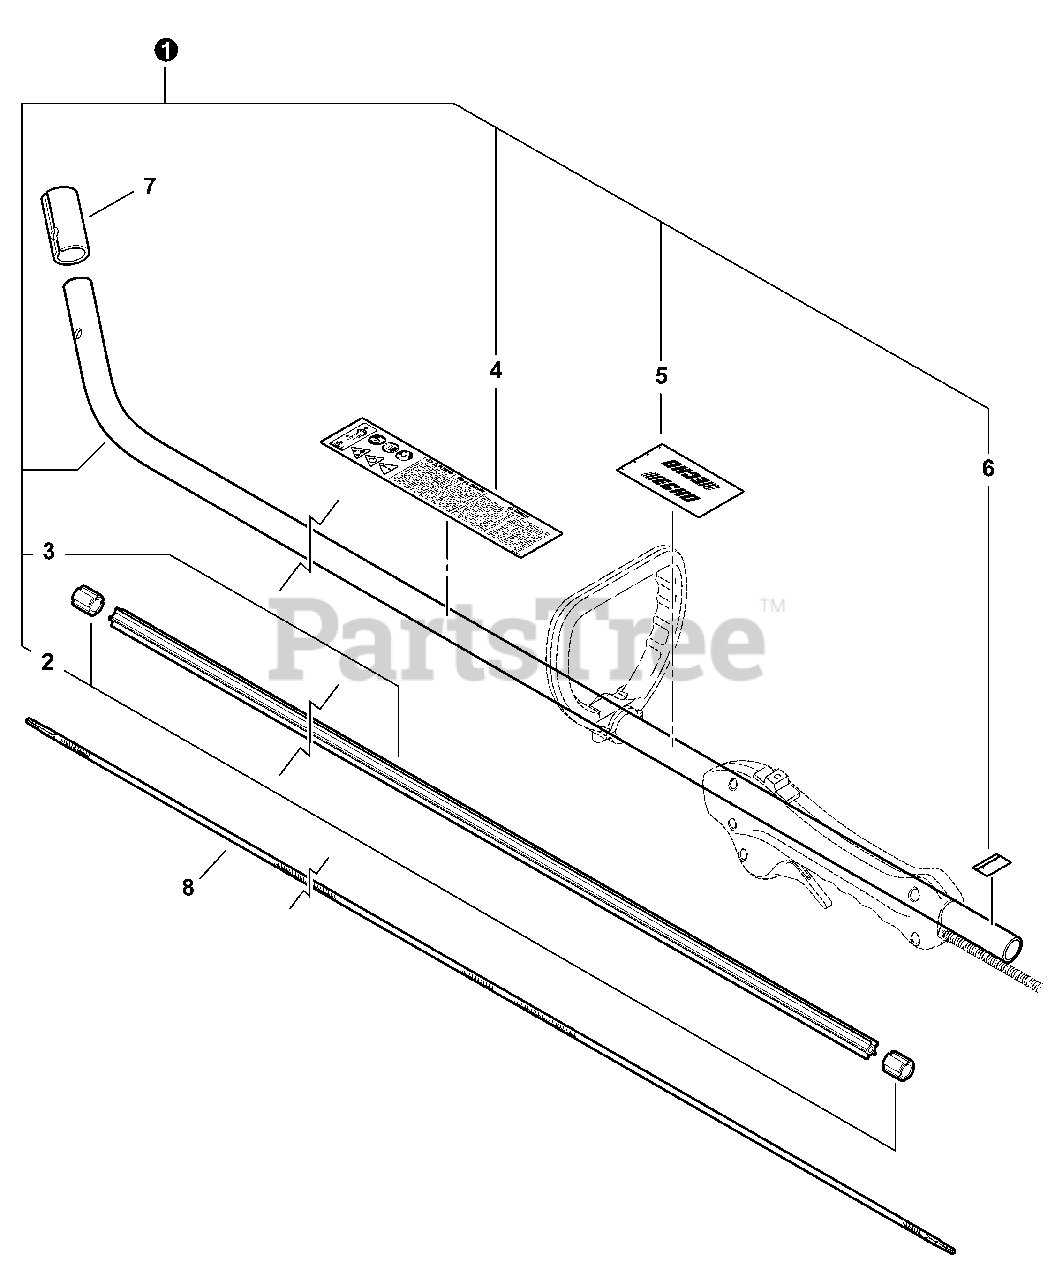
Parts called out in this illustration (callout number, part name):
1	MAIN PIPE ASSY
3	LINER - FLEXIBLE
4	LABEL, CAUTION
5	LABEL, HANDLE LOCATION
6	LABEL - ALIGNMENT
8	DRIVESHAFT - FLEXIBLE
